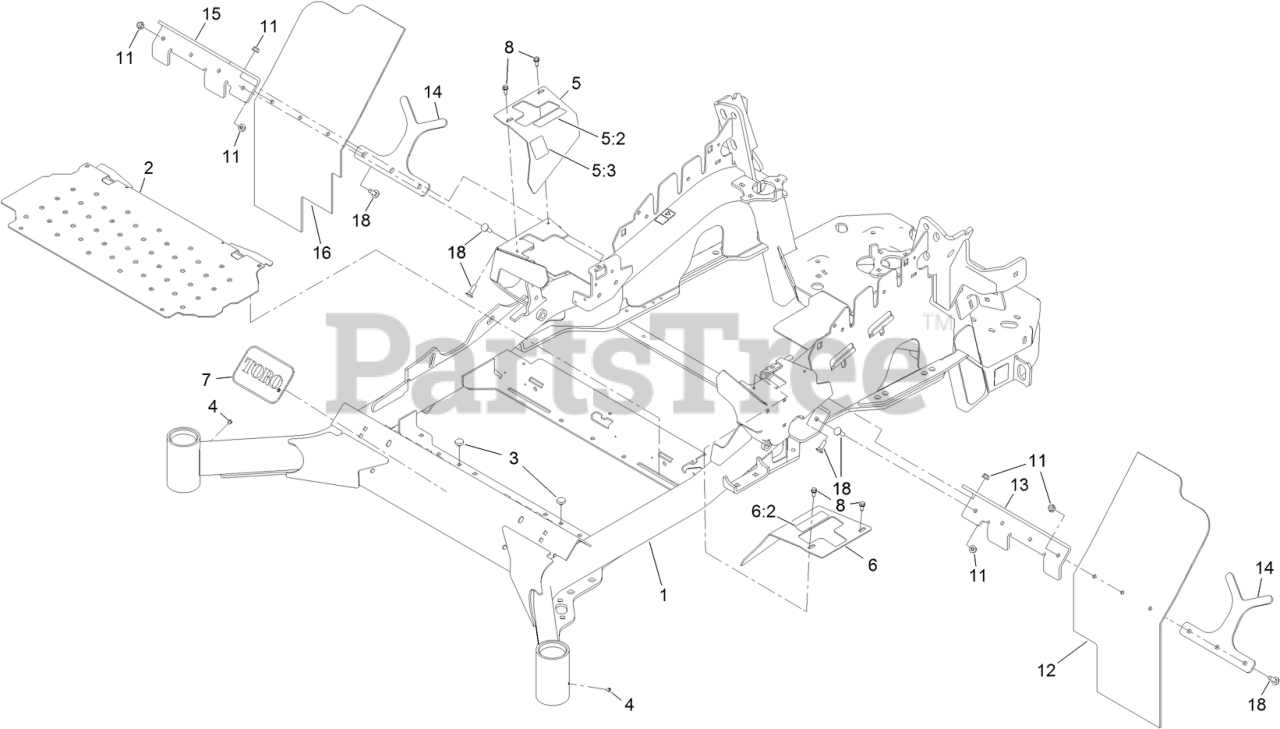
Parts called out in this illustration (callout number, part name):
1	MAINFRAME ASM
2	FLOORPAN
3	BUMPER
5	RH MOTION CONTROL COVER ASM
5:2	DECAL-CONTROL, MOTION
5:3	DECAL-PARK BRAKE, CE
6	LH MOTION CONTROL COVER ASM
6:2	DECAL-CONTROL, MOTION
7	DECAL
8	SCREW-HWH
11	NUT-HF, NI
12	MUD FLAP
13	BRACKET-MUD FLAP, LH
14	SUPPORT-MUD FLAP, REAR
15	BRACKET-MUD FLAP, RH
16	MUD FLAP
18	BOLT-CARR
